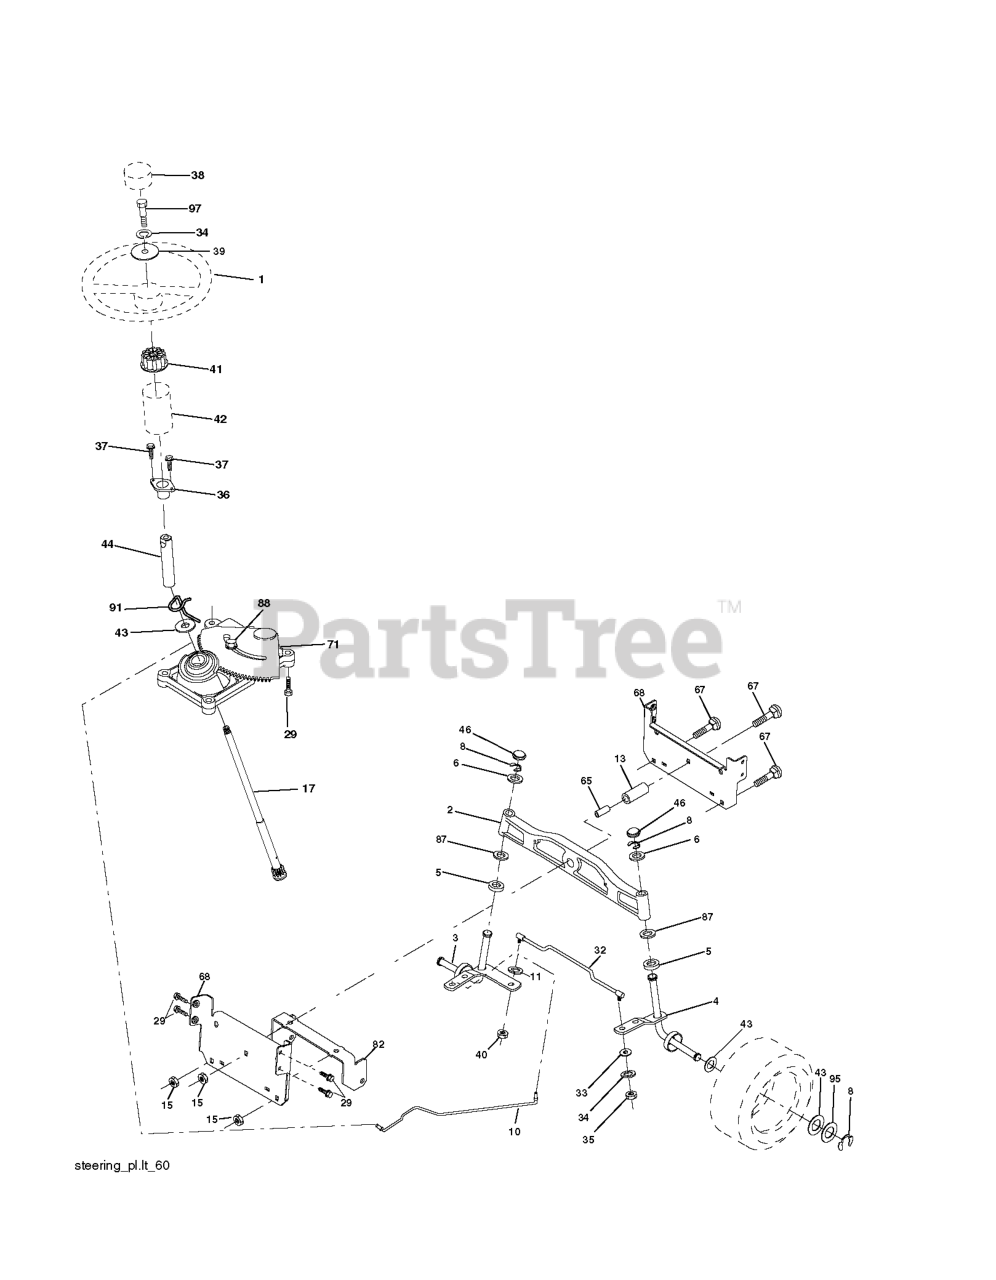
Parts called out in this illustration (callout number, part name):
1	STEERING WHEEL
2	AXLE ASSY FRONT
3	SPINDLE.ASM.LH.15"TIRES
4	SPINDLE.ASM.RH.15"TIRES
5	THRUST WASHER
10	DRAGLINK.15".TIRES.2001
11	WASHER, LOCK 3/8
13	TUBE, PIVOT AXLE
15	NUT
17	SHAFT.EXTEN.STRG.SPLINE
29	SCREW, 3/8-16X3/4
33	WASHER M
34	WASHER.LOCK.HVY.HLCL.SPR.5/16
35	NUT, CROWNLOCK
36	BUSHING, STEERING
37	SCREW.TT.#10-32X.5.3/8.FLANGE
38	INSERT.CAP.STRG.WH.GRAY
39	WASHER.11/32
40	NUT CROWNLOCK 3/8-24
41	ADAPTER, WHEEL STNG..
42	BOOT, STEERING
44	SHAFT STEERING SPLINE
46	CAP.SPINDLE.BLACK
65	SPACER BRACE AXLE
67	BOLT CARRIAGE
68	BRACE.AXLE.15"TIRES
71	STEERING ASM
82	BRACKET.SUSP.CHASSIS.FRONT.15
87	WASHER, FLAT .781 X 1 1/2"
88	BOLT, SHOULDER 7/16-20
91	CLIP.STEERING
95	WASHER.HARDENED
